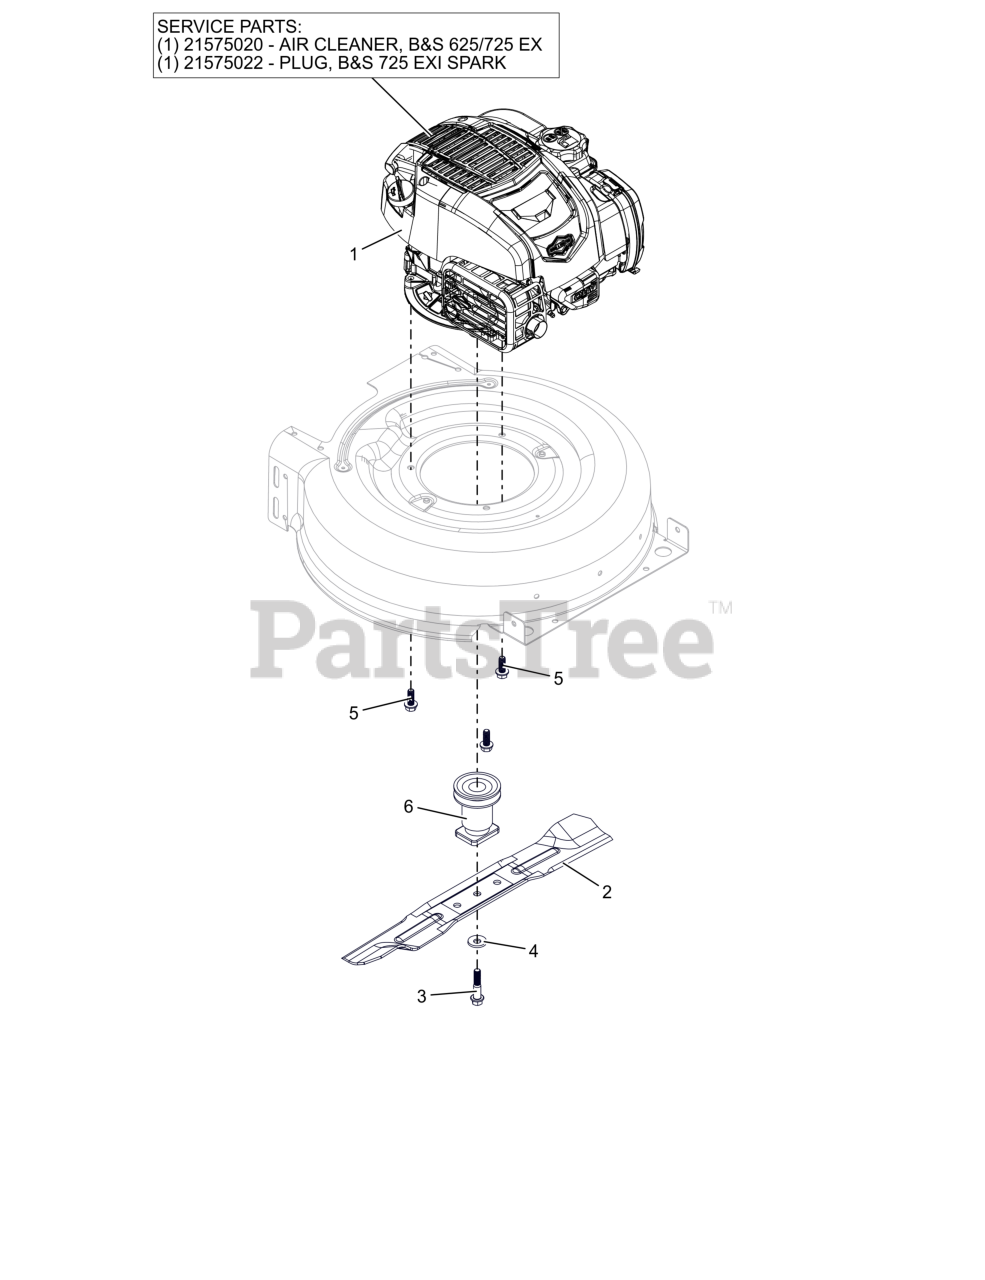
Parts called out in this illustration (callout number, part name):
1	ENGINE, BRIGGS 725 EXI MNS
1	AIR CLEANER- B&S 625/725 EX
1	PLUG- B&S 725 EXI SPARK
2	BLADE, MOWER 21" HIGH LIFT
3	BLT-SHLDR .435X1.00X.38-24
4	WSHR, BLVL- .440X1.130X.120
5	SCR-TAP, 3/8-16X1.00 HWH
6	SPCR, BLADE - SINGLE
